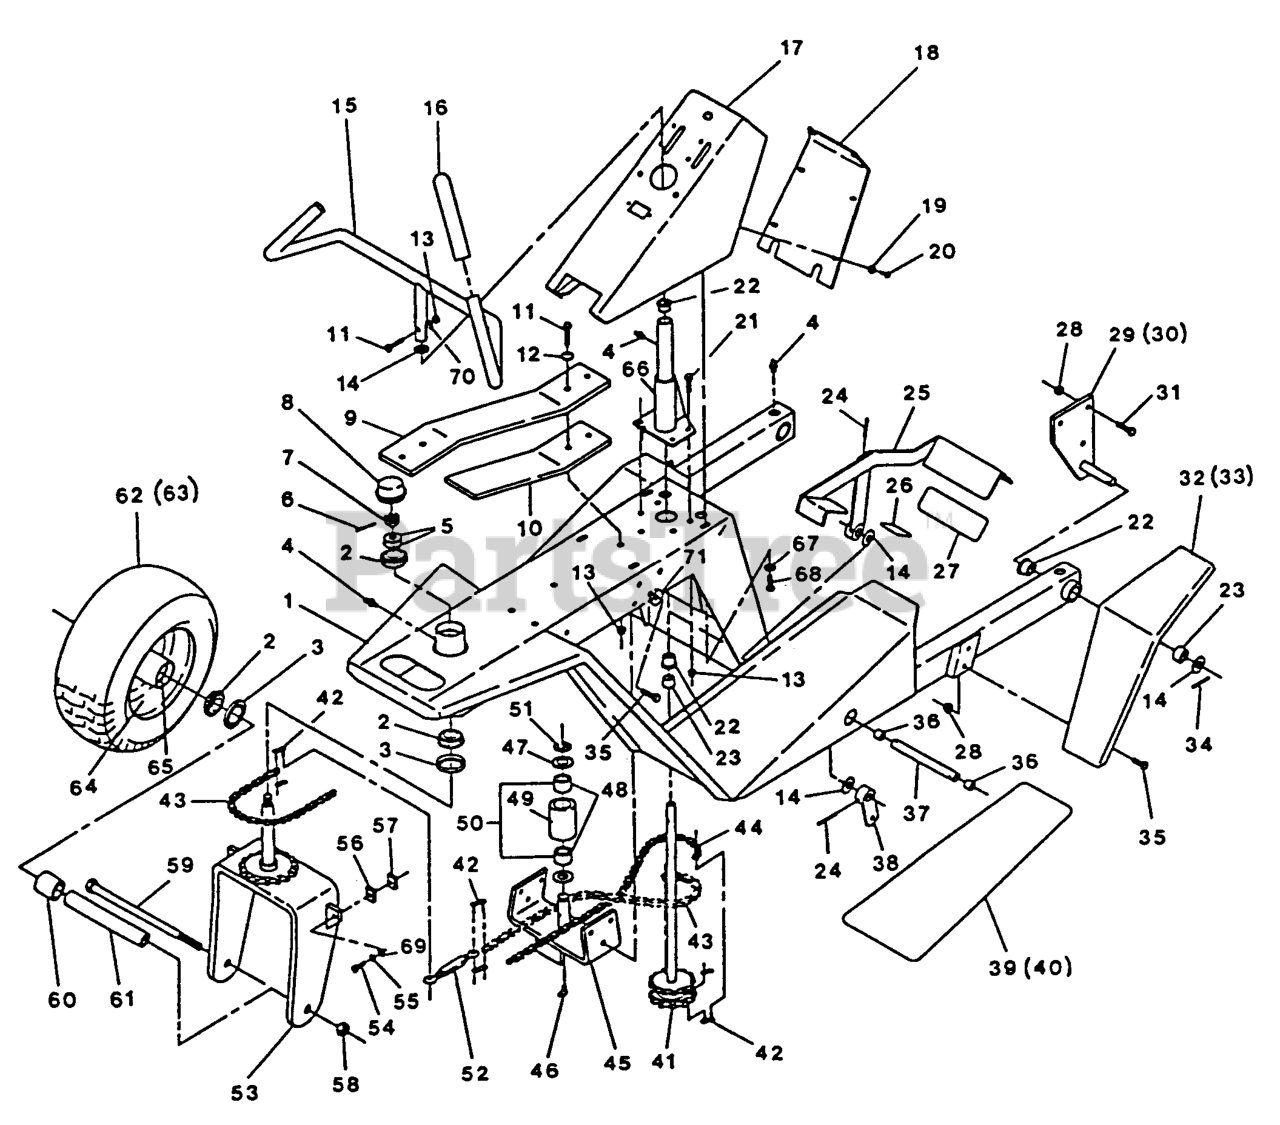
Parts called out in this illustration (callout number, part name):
2	Cone-Bearing Tapered Roller
3	SEAL-GREASE
8	CAP-GREASE
20	SCRWMACH PHS
23	SLEEVE,BEARING
24	PIN,ROLL
27	PAD,ANTISKID
29	WLD,BRACKET PIVOT RH
38	WLD,FOOT PEDAL LEVER
39	PAD,ANTISKID RH
40	PAD,ANTISKID LH
43	CHAIN-#40-35 PITCH
46	1481
47	WASHER-SPACER
48	BUSHING BRONZE 2900
51	RING-SNAP
53	WLD,STEER MOUNT
55	WASHER-LOCK
59	SCRW,CAP HH
60	SPACER,WHEEL SHORT
61	BUSHING, WHEEL - PLT
62	ASM,WHEEL & TIRE
63	TIRE ONLY 8NHS
64	WHEEL 8.00 W/HUB
65	CUP-BEARING
71	WASHER-LOCK
